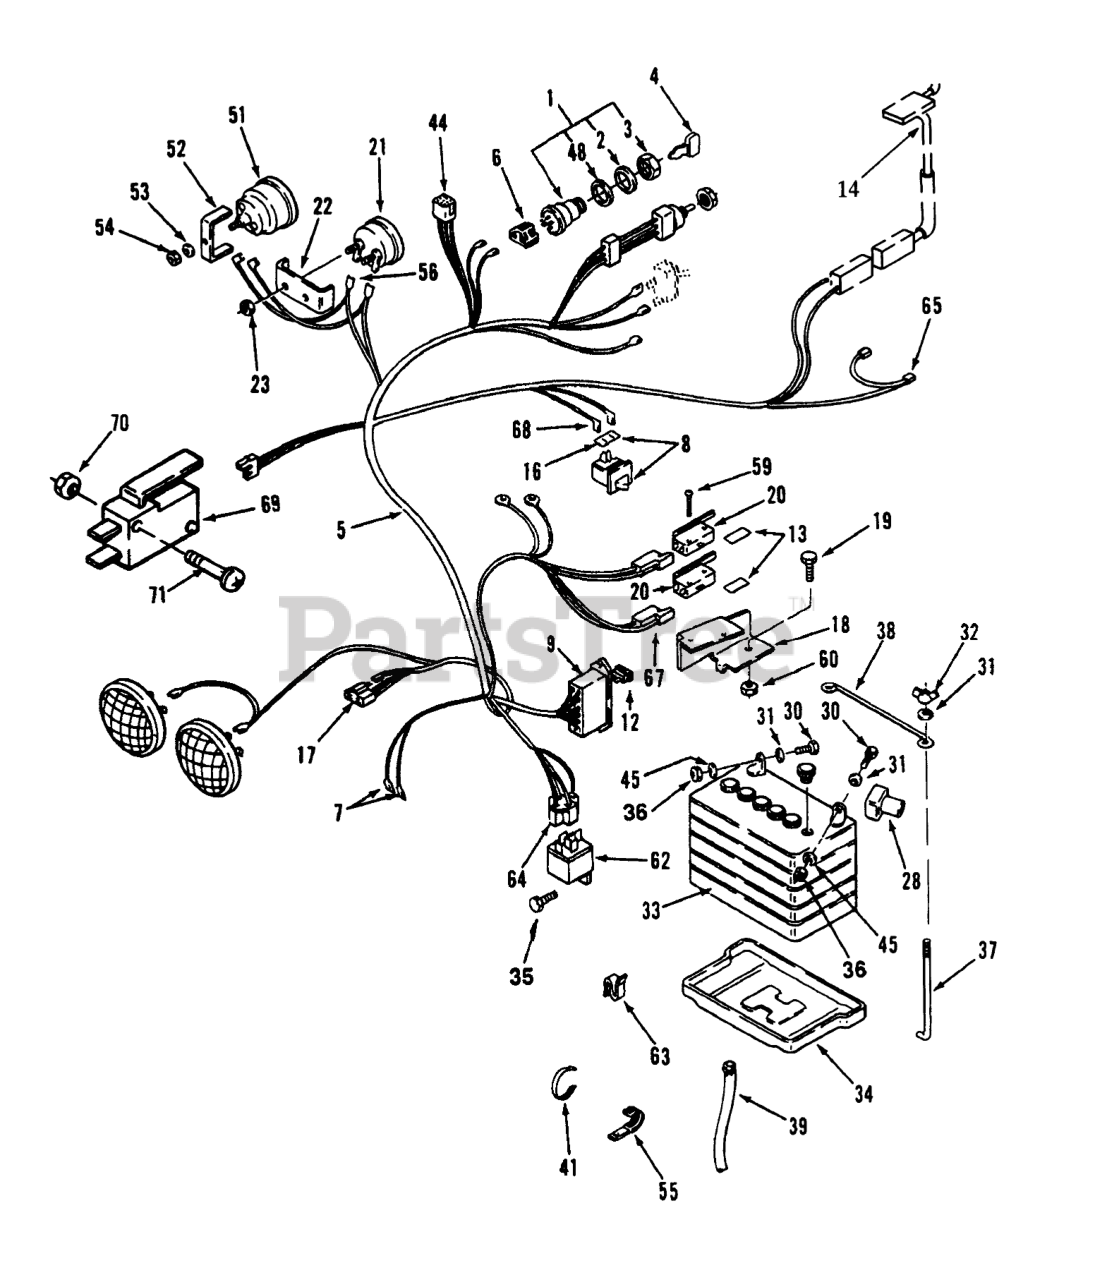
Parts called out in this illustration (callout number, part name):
1	IGNITION SWITCH ASM
2	WASHER-LOCK
4	KEY-IGNITION
5	Wiring Harness (Incl. Ref. #6,7,9,17,44,65 & 68)
6	CONNECTOR BODY ELECT
7	TERMINAL 10
8	Switch-Clutch Interlock,(Incl. Ref. #16)
9	FUSE-HOLDER 4 WAY
12	FUSE-BLADE, 15 AMP
13	BARRIER - SWITCH
14	SWITCH-SEAT
16	SHIELD-DIRT SPST
17	5-CONTACT CONN BODY
18	BRACKET-SWITCH
19	Bolt
20	SWITCH
21	VOLTMETER
22	CLAMP-MOUNTING
23	HEX NUT 10-32 E.S.
28	Boot
30	SCREW-HH
31	WASHER-FLAT
32	Nut
33	Battery
34	TRAY-BATTERY
36	NUT-LOCK, INSERT
37	HOOK-BATTERY RETAIN
38	HOLDDOWN-BATTERY
39	TUBE-21" BATTERY DRAIN
41	PLASTIC TIE
44	Terminal
45	WASHER-LOCK
48	WASHER
51	Meter-Hour(Incl. Ref.#52-54)
52	CLAMP-HOUR METER
53	Lockwasher
54	Hex Nut
55	CLIP
59	SCREW-PHL 4-40X1 1/4
60	NUT-HEX
62	RELAY
63	CLIP-CABLE
64	TERMINAL 10
65	Sur-Plug
68	Terminal
69	SWITCH
70	NUT-HEX
71	Screw
